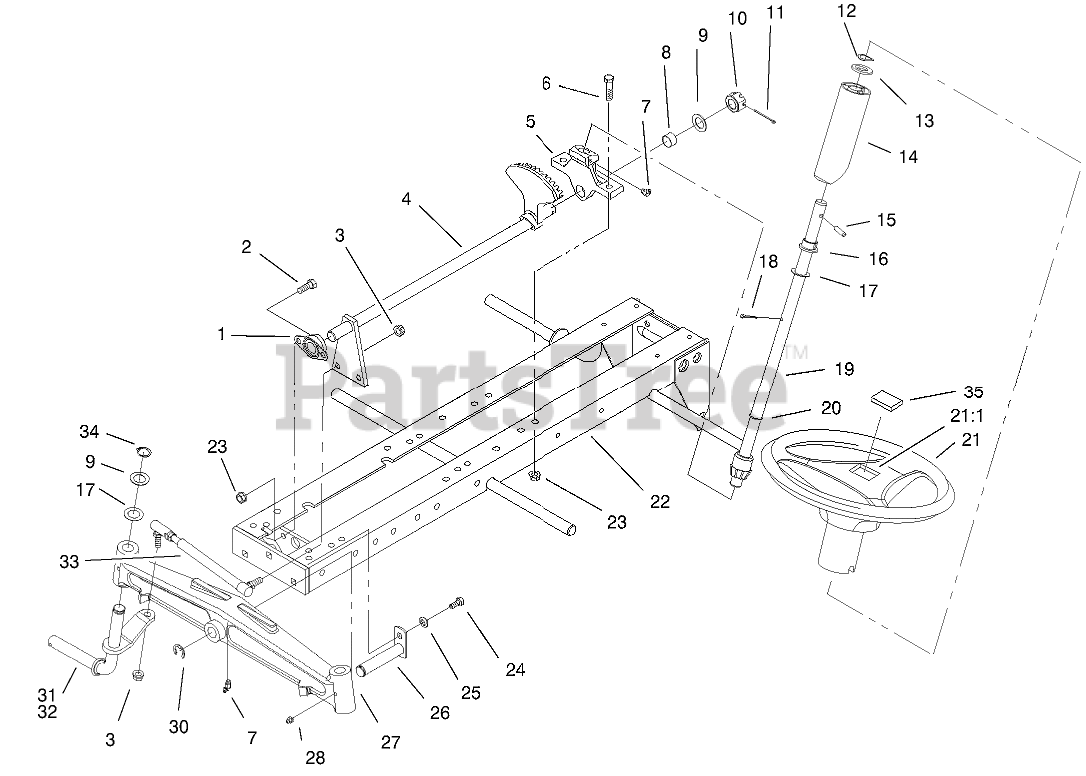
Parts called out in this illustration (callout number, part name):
1	BEARING-FLANGED
2	SCREW-HH
3	NUT-LOCK
4	LOWER STEERING ASM
5	SUPPORT-LOWER, STEERING
6	SCREW-HH
7	FITTING-LUBE, 45 DEG
8	BEARING-BRONZE
9	WASHER
10	NUT-HEX, SLOTTED
11	PIN-COTTER
12	WASHER-BOWED
13	WASHER-FLAT
14	TUBE-STEERING
15	PIN-ROLL
16	BEARING-FLANGED
17	WASHER-SHIM
18	PIN-COTTER
19	STEERING SHAFT ASM
20	O-RING
21	WHEEL-STEERING
21:1	COVER-WHEEL, STEERING
22	FRAME ASM
23	NUT-LOCK, NI
24	SCREW-HH
25	WASHER-LOCK
26	PIN AND PLATE ASM
27	AXLE-FRONT
28	FITTING-GREASE
30	E-RING
31	LH Spindle Wa (only on: 73429)
31	Spindle-RH, Wa (only on: 73449)
32	Spindle-LH, Wa (only on: 73449)
32	Spindle-RH, Wa (only on: 73429)
33	TIE ROD ASM
34	RING-RETAINING
35	DECAL
